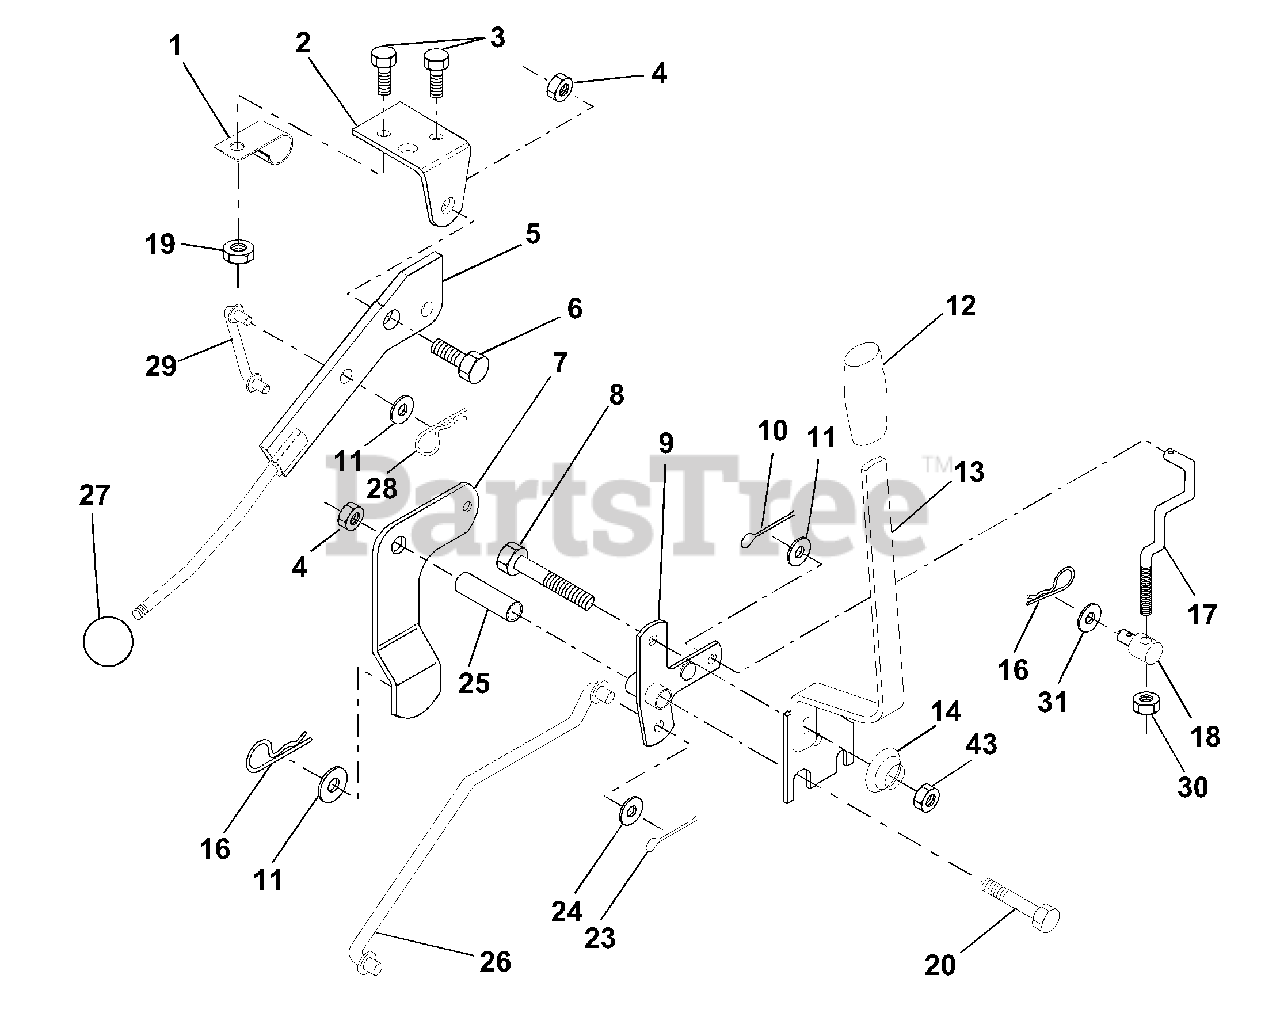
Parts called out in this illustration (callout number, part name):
1	Clip, Insulated
2	Bracket, Mower Clutch
3	Bolt, Fin. Hex 1/4-20 UNC x 1/2 Gr. 5
4	Nut, Crownlock 3/8-16 UNC
5	Assembly, Clutch Lever
6	Bolt, Shoulder
7	Assembly, Mower Clutch Arm
8	Bolt, Hex 3/8-16 UNC x 2-1/4
9	Assembly, Bellcrank Lift
10	Pin, Cotter 1/8 x 3/4
11	Washer 13/32 x 13/16 x 16 Ga.
12	Grip, Handle
13	Assembly, Lift Handle
14	Spring, Compression
16	Retainer, Spring
17	Link, Front Lift
18	Trunnion, Threaded 3/8-16
19	Nut, Crownlock 1/4-20
20	Bolt, Fin. Hex 3/8-16 UNC x 2-3/4
23	Pin, Cotter 1/8 x 1
24	Washer 17/32 x 1 x 12 Ga.
25	Tube, Spacer
26	Rod, Mower Lift
28	Retainer Spring
29	Link, Mower Clutch
30	Nut Hex Jam 3/8-16 x 1.30
31	Washer 13/32 x 1-1/4 x 12 Ga.
43	Nut Lock Flg 3/8-16
